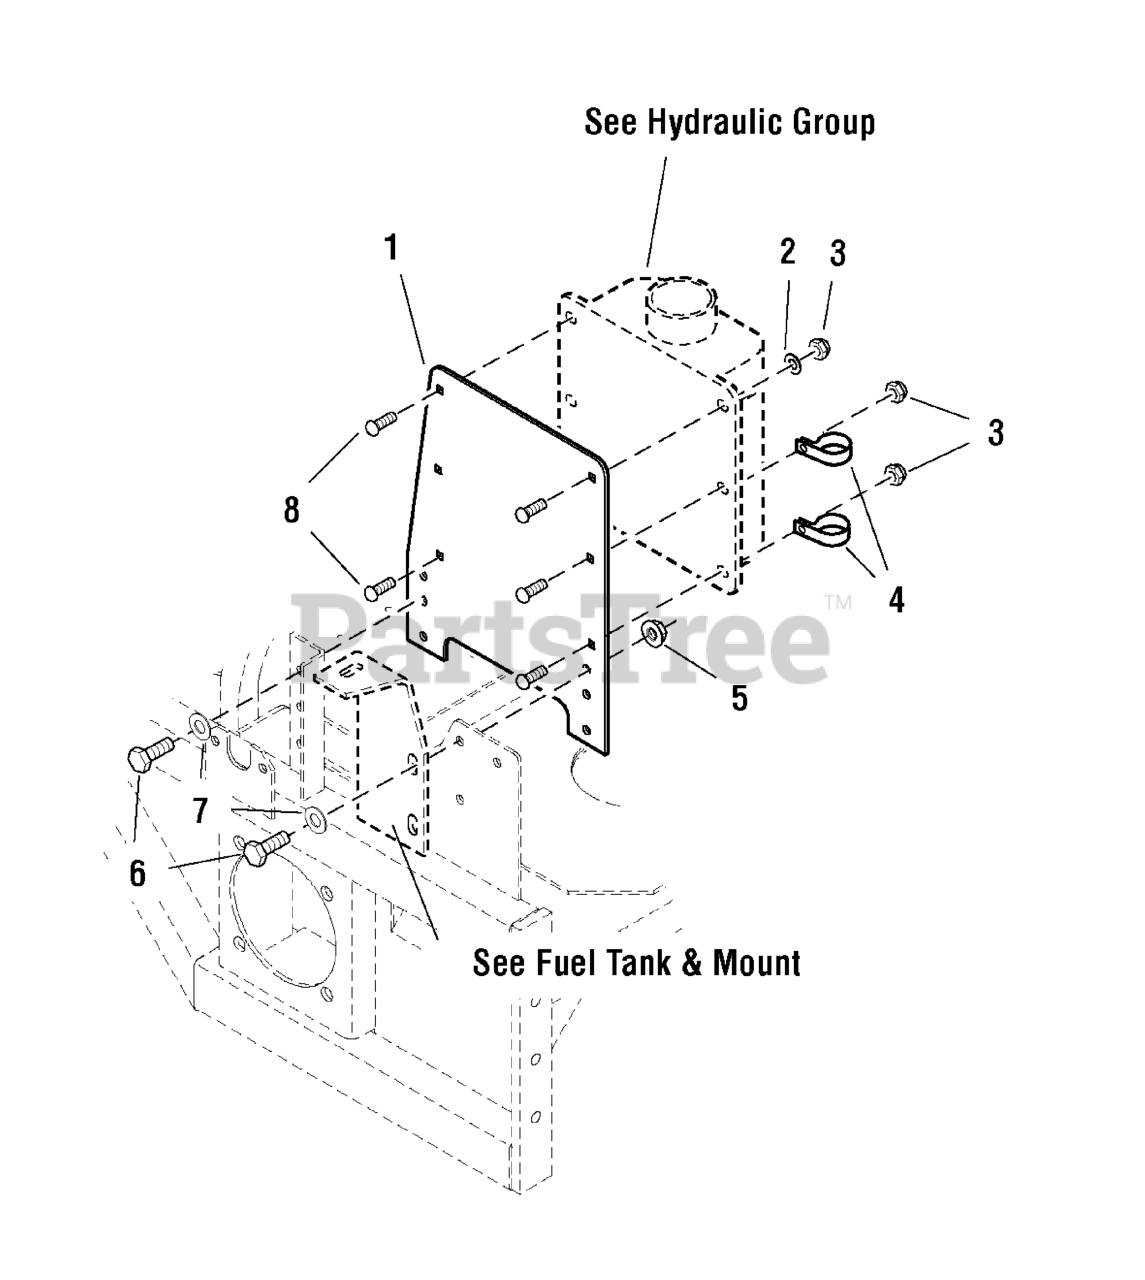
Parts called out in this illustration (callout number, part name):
1	PLATE, Tank Mount
2	WASHER, 1/4 SAE
3	NUT, 1/4-20 HEX NYLON LOCK
4	CLAMP, Vinyl
5	NUT, 5/16-18 HEX SERRATED FLANGE (SMALL)
6	BOLT, 5/16-18 X 1 GD5 YZ
7	WASHER, 5/16" SAE
8	BOLT,1/4-20X0.750,GR5,STD NECK,SQ,ZC/CL
